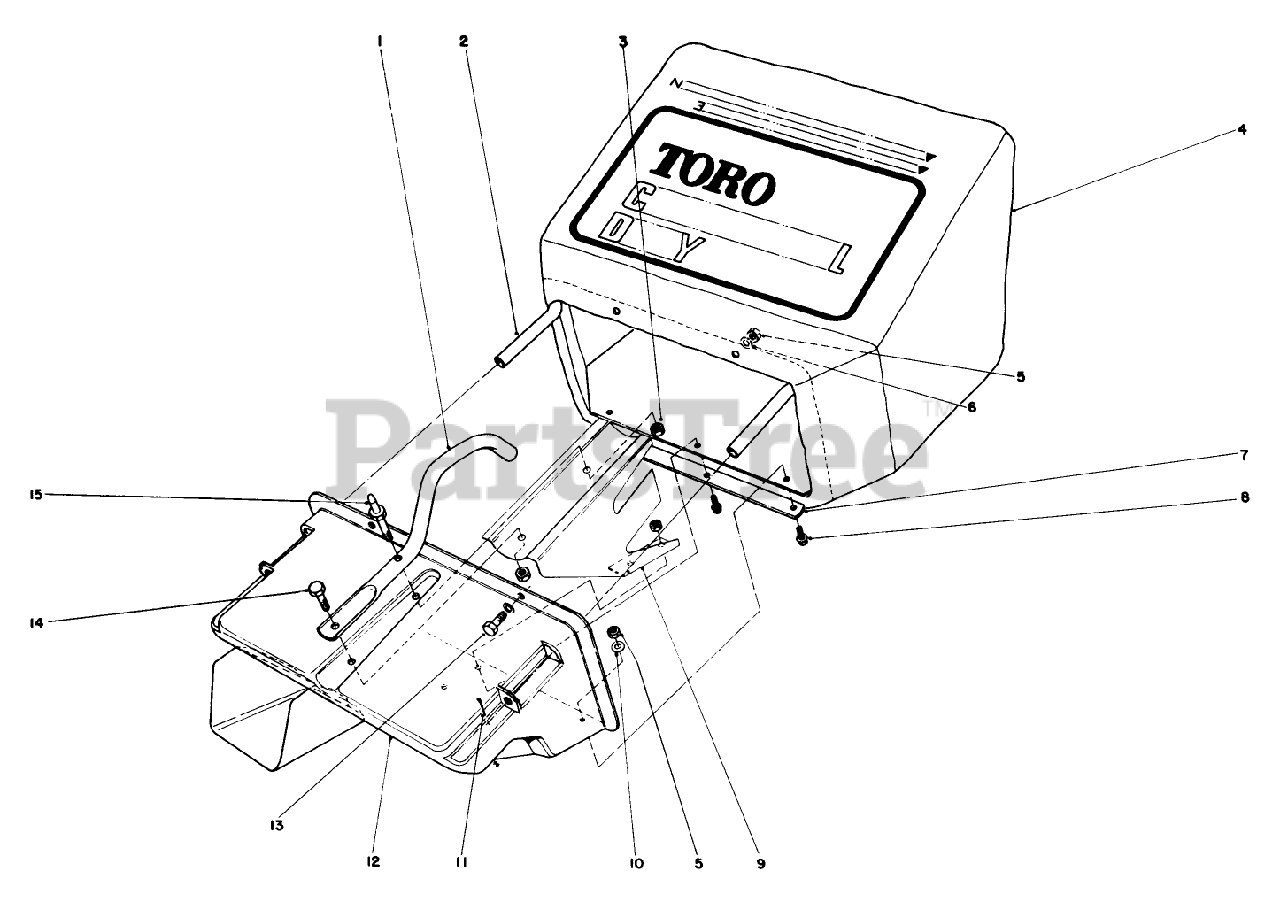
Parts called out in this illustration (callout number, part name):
1	BAG HANDLE
2	Bag Frame
3	Nut
4	Grass Bag
5	Nut
6	Washer
7	BAG RETAINER
8	SCREW-HWH
9	BAFFLE-BAG SHELL
10	WASHER-FLAT
11	PIN-COTTER
12	Bag Shell
13	Screw
14	SCREW-HH
15	HANDLE STUD
